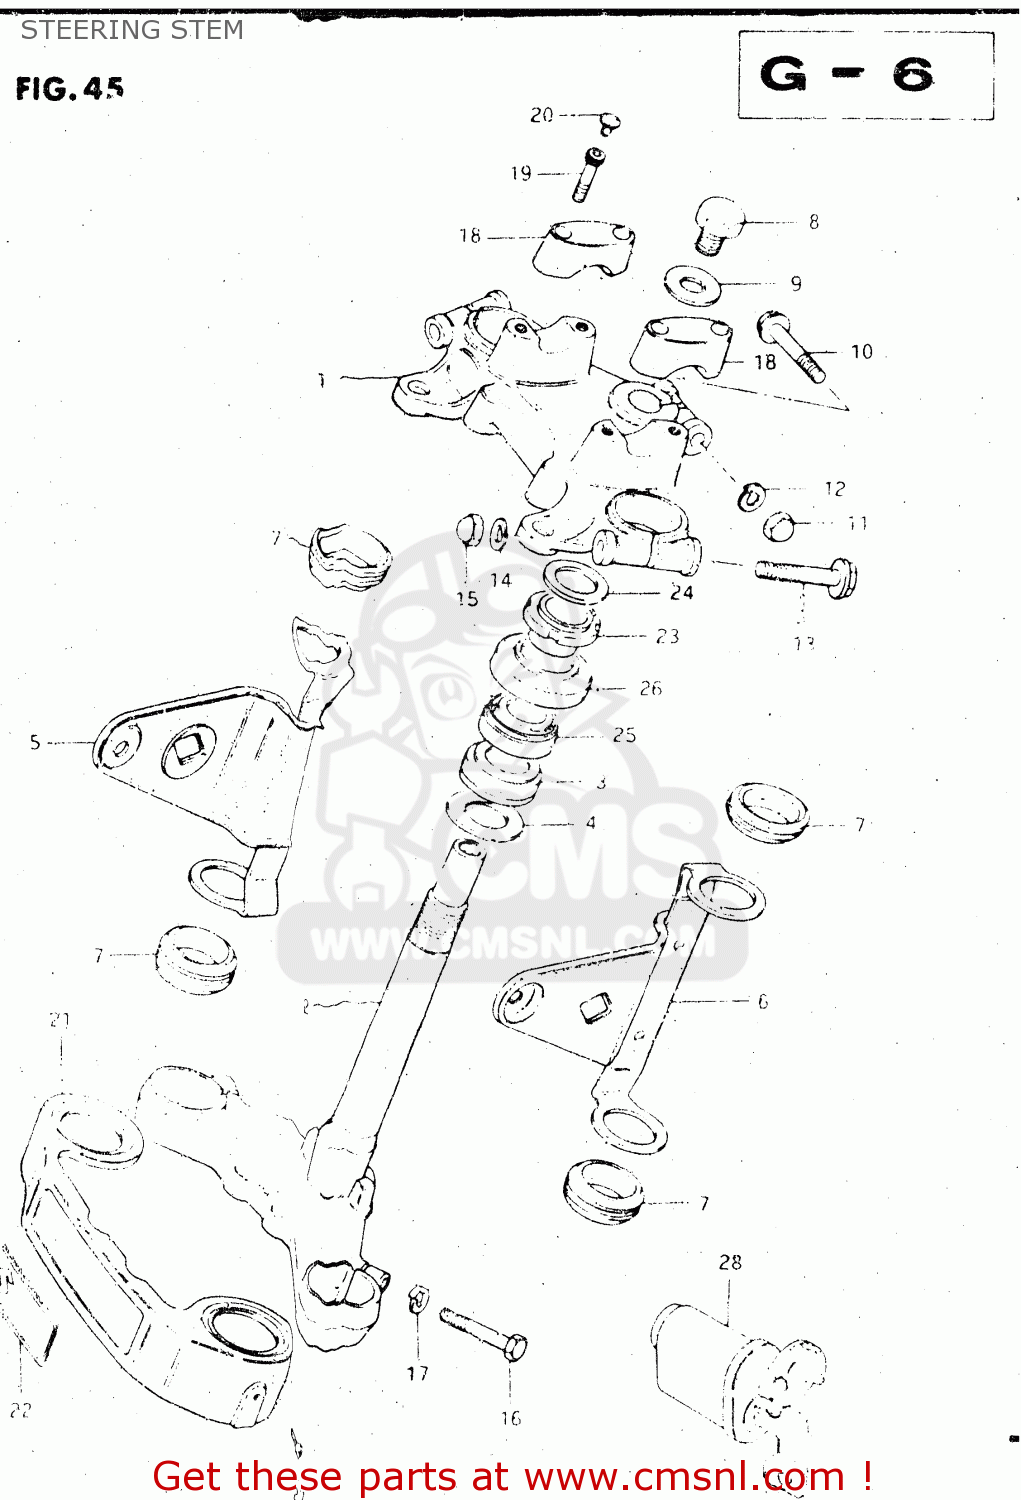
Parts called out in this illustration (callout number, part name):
1	HEAD,STEERING STEM
2	STEM,STEERING
3	BEARING
4	WASHER,THRUST
5	BRACKET,HEADLAMP,RIGHT
6	BRACKET,HEADLAMP,LEFT
7	CUSHION,HEADLAMP BRACKET
8	BOLT(12X20)
9	WASHER (12.5X26X1.6)
10	BOLT
11	NUT,M8X1.25X12
12	LOCK WASHER
13	BOLT 10X55
14	LOCK WASHER
15	NUT
16	BOLT 10X40
17	LOCK WASHER
18	HOLDER,HANDLEBAR(BLACK)
19	BOLT
20	CAP(OD:14.5)
21	COVER,FRONT FORK
22	EMBLEM
23	NUT,STEERING STEM
24	WASHER(18.5X24X1)
25	TAPER,ROLLER BEARING
26	DUST SEAL,STEERING UPR
27	SCREW 5X6
28	LOCK ASSY, STEERING (NEIMAN TYPE EXECUTE
